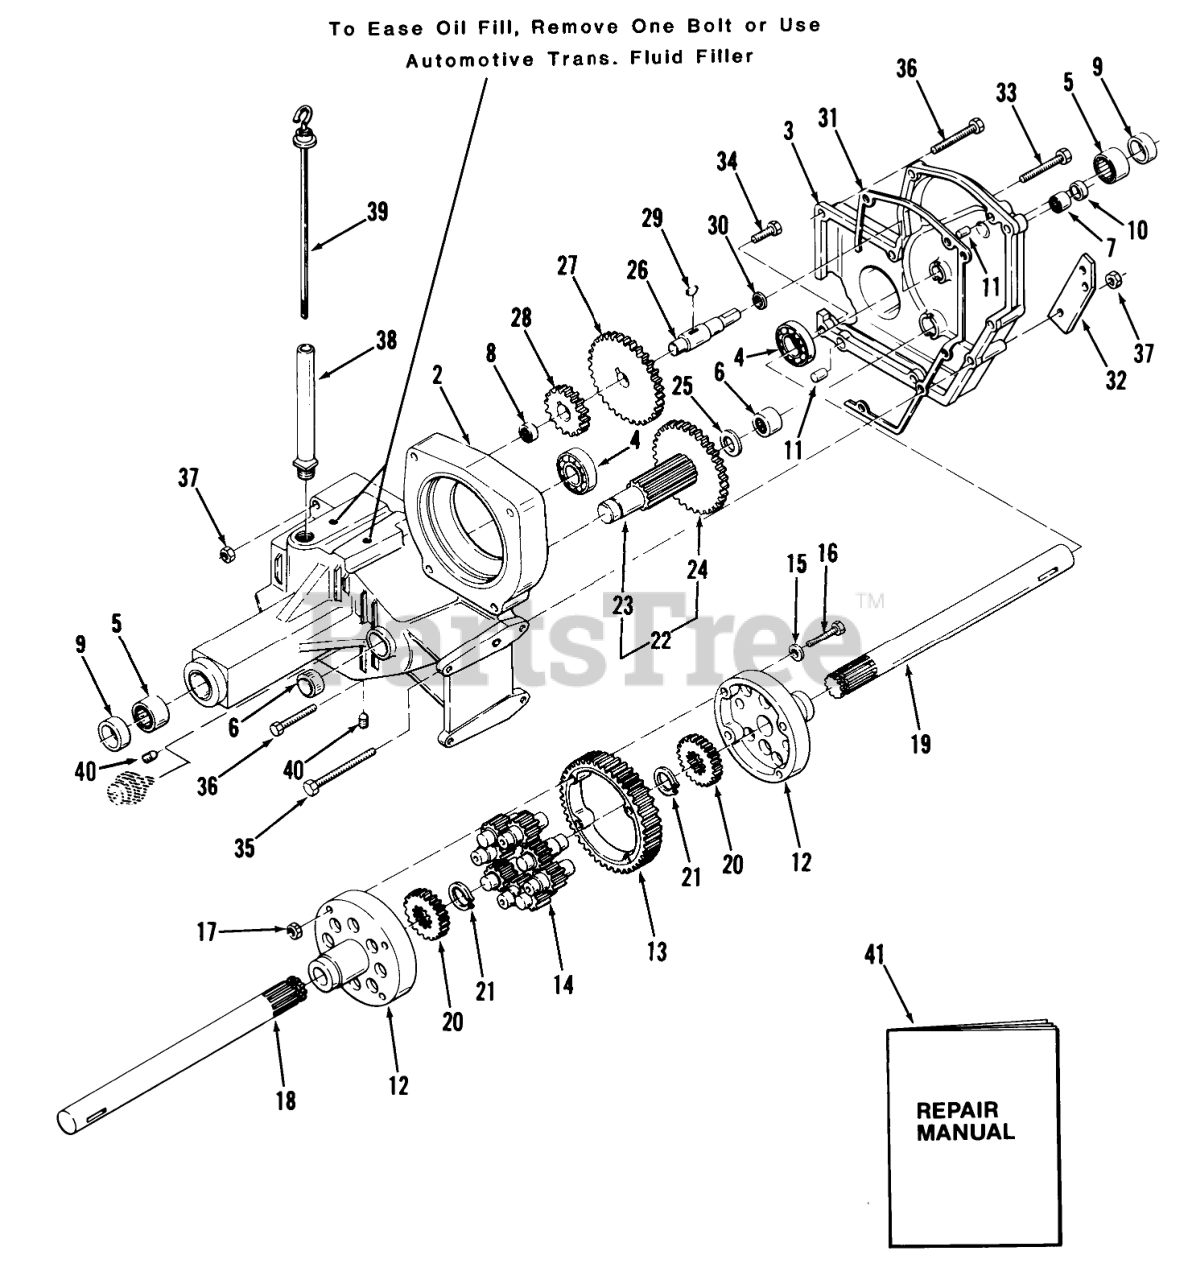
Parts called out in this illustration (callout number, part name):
2	CASE-TRANS RH
3	CASE TRANS LH
4	BEARING-BALL
5	BEARING
6	BEARING-NEEDLE
7	NEEDLE BEARING
8	BEARING-NEEDLE
9	SEAL-OIL
10	Seal
11	PIN-LOCATING
12	END CAP-DIFFERENTIAL
13	GEAR-DIFFERENTIAL RING, 43T
14	GEAR-PINION, 11T
15	WASHER
16	BOLT-HEX
18	AXLE-REAR RH
19	AXLE-REAR LH
20	GEAR-AXLE DIFFERENTIAL
21	RING-SNAP
22	ASSY GEAR
22	GEAR ASM
23	PINION SHAFT
24	GEAR 46T
25	WASHER-THRUST
26	SHAFT GEAR
27	GEAR 46 TEETH
27	Gear 44 Tooth
28	GEAR 20 TEETH
28	GEAR 22T
29	Key
30	Race Thrust
31	GASKET-TRANSMISSION
32	BRACKET-BRAKEB
33	Bolt
34	Bolt
35	Hex Bolt
36	HHCS
37	NUT
38	NIPPLE-TRANS FILL
39	ASSY-DIPSTICK
39	Dipstick
40	PLUG 1/4 PIPE ALLEN
41	Repair Manual
